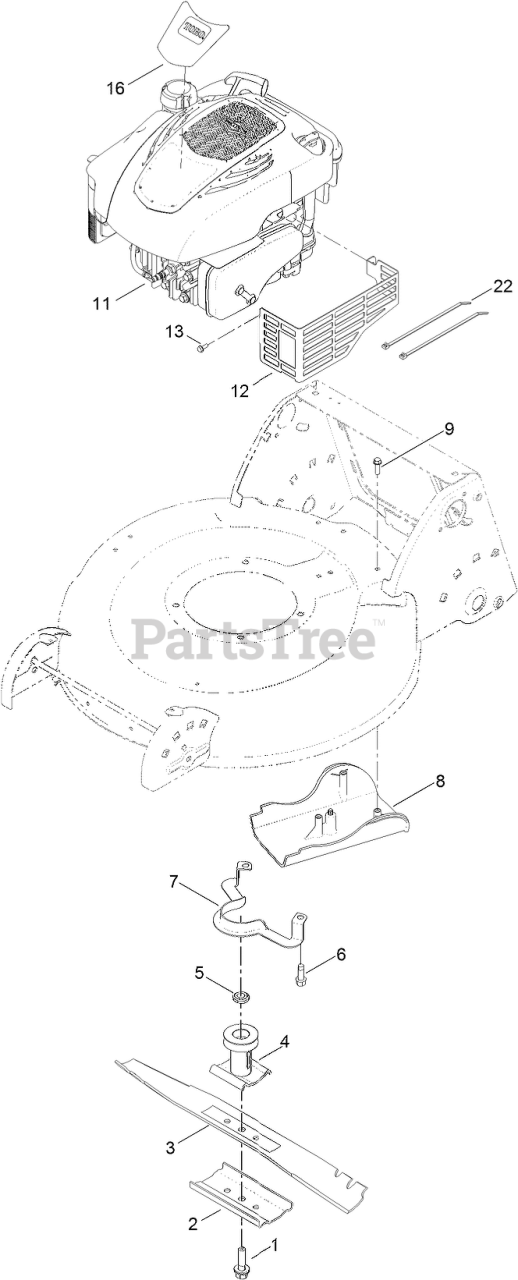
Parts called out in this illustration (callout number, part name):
1	BOLT-BLADE
2	SUPPORT-BLADE
3	BLADE-21 INCH
4	DRIVER-BLADE
5	Spacer-Driver
6	SCREW-TAPTITE
7	Guide-Belt
8	COVER-BELT
9	SCREW-HWH
12	SHIELD-MUFFLER
13	SCREW-TAPTITE
16	DECAL-SHROUD
22	TIE-CABLE
